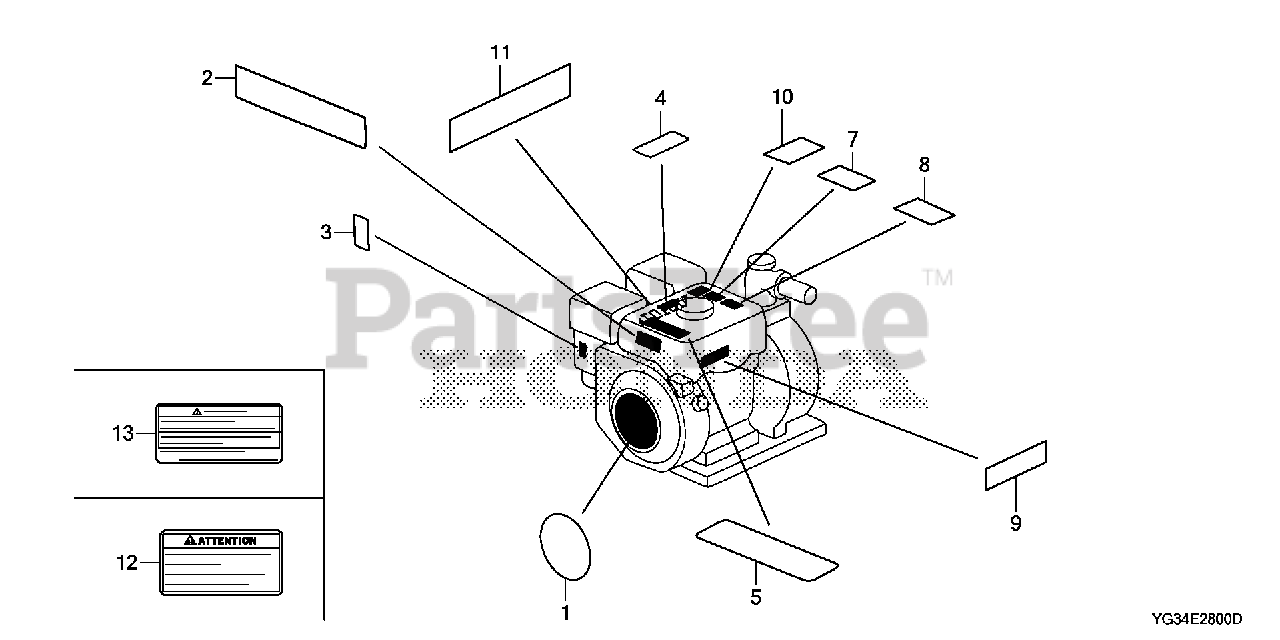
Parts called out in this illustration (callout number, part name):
1	EMBLEM (GX160)
3	MARK, CHOKE
8	LABEL, OPERATOR WARNING (ENGLISH)
9	MARK, OIL ALERT (ENGLISH)
10	MARK, EX. CAUTION (ENGLISH)
11	LABEL, SPARK WARNING
